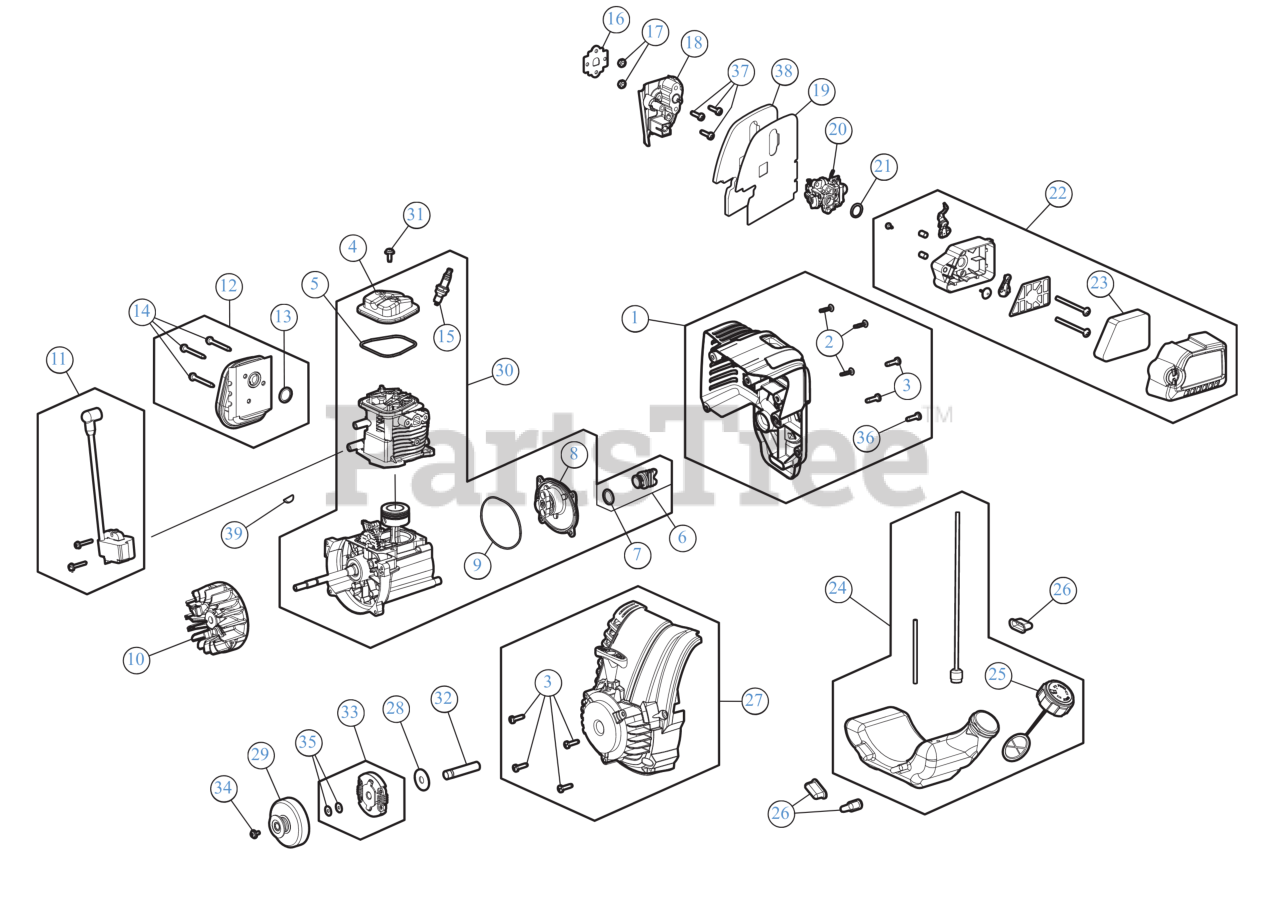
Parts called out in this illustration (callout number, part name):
1	REAR ENGINE CVR
2	SCREW 8-16 x 3/4
3	SCREW M5-0.8 x 19
4	ROCKER COVER
5	O-RING
6	OIL PLUG
7	RING, OIL PLUG (AC
8	CRANKCASE COVER
9	O-RING CRNKCSE CVR
10	FLYWHEEL ASSEMBLY AC3.1
11	MODULE ASSEMBLY
12	MUFFLER ASSEMBLY
13	GASKET/MUFFLER
14	SCREW M5 x 44MM
15	SPARK PLUG 4 CYCL
16	GASKET/INSULATOR
17	NUT 10-32
18	CARB INSULATOR
19	GASKET
20	CARBURETOR
22	AIR CLEANER COVER
23	AIR FILTER
24	FUEL TANK ASSEMBLY
25	FUEL CAP ASSEMBLY 43MM-6 W/O HOLE
26	FUEL TANK PADS
27	STARTER HOUSING (LIB RED)
28	WASH, CLUTCH O.D. 1.155 +/- .0
29	CLUTCH DRUM/PULLEY
30	SHORT BLOCK
31	SCR, VALVE COVER
32	SPACER :2.165"
33	CLUTCH WITH SPACER
34	SCREW 8-32X.375 PH S
35	WASH, NORAM CLUTCH
36	SCR, M5 x 15.8MM
37	SCREW, M5 X18
38	HEAT SHIELD
39	WOODRUFF KEY #403-.125 x .375
